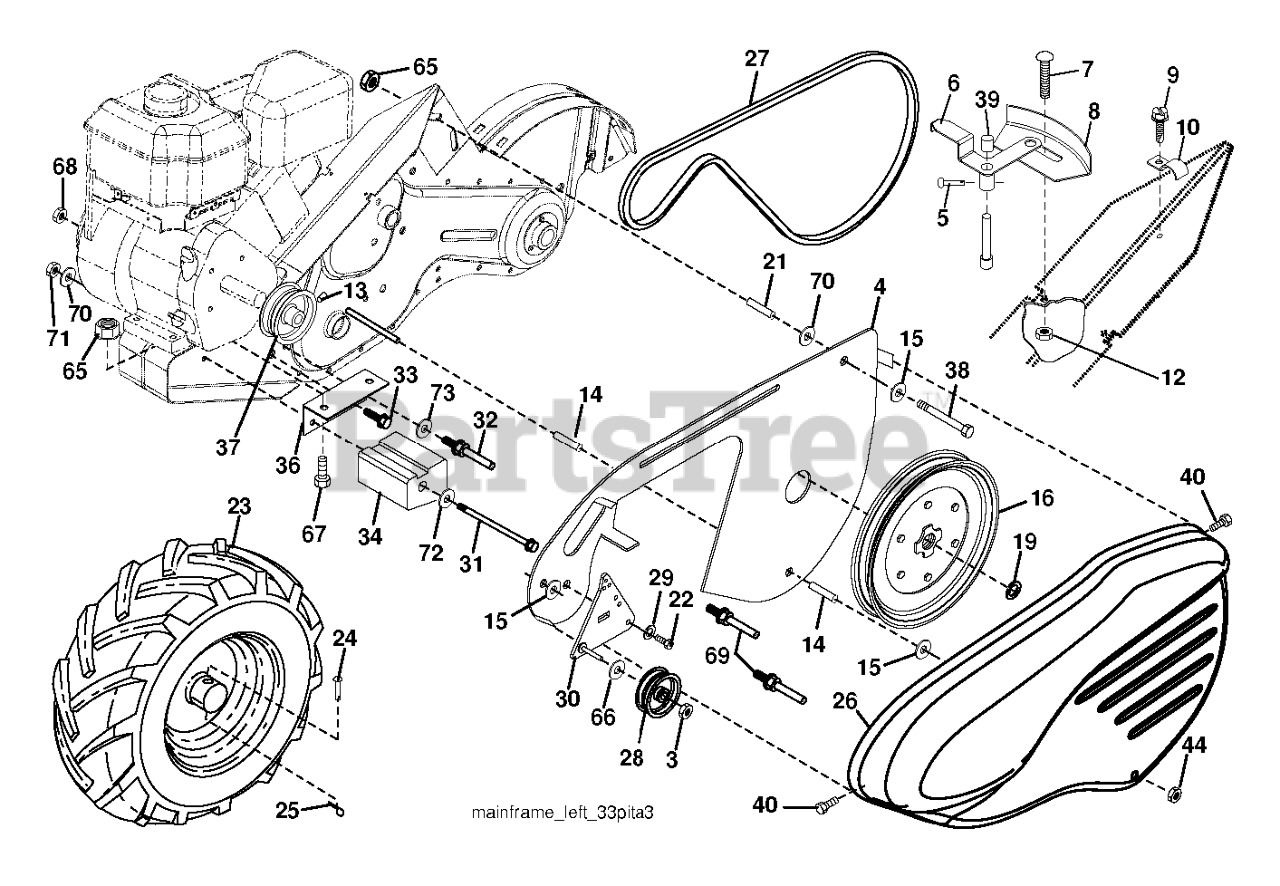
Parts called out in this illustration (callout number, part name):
1	DECK.WELDMENT.54"MS418
3	LOCKNUT
4	SHIELD.INNER.BELT.GUARD.RT.BLA
5	PIN.SPIROL.FLARED
6	COVER.MANDREL.LH.54"20
6	LEVER.ASM.SHIFT.RED
7	COVER.MANDREL.RH.54.20
8	BOLT.WASHER.ASM.7/16-2
8	PANEL.INDICATOR.SHIFT.BLACK.
9	TAPPING SCREW
10	CLIP.PLATED
11	BLADE.BAGGING.54"
12	ROD.ANTI.SWAY.48/54"K4
12	NUT
13	SHAFT ASM MANDREL
14	RP.HOUSING.MANDREL.4PT.
14	SPACER-SPLIT.327 X .42
15	WASHER.FLAT.34X1.38X22
16	WASHER
16	SHEAVE, TRANSMISSION
18	BOLT
19	PIN.COTTER.5/16.BOW TI
19	RETAINING RING LT
21	LOCKNUT
21	SPACER SPLIT
23	WHEEL.ASM.DRT.13X5-6.LT.SILVER
24	CAP-SLEEVE LT
24	RIVET
25	SPRING, TORSION
25	RETAINER M
26	NUT PUSH M
26	GUARD.BELT.TILLER.ORANGE
27	DEFLECTOR
27	V-BELT
28	PULLEY-IDLER TI
29	ROD.HINGE
30	SCREW, WASHER HEAD
30	BRACKET.IDLER.ASM.LONG
31	WASHER.SPACER.MANDREL
31	BOLT.FIN.HEX.3/8-16UNC X 11.5
32	PULLEY/MANDREL
32	SHIFT ARM CRT
33	NUT.FLANGE.LOCK.TOP
33	BOLT
34	COUNTERWEIGHT.LH
36	BRACKET.REINFORCEMENT.LH.PNT
37	RP.ENGINE PULLEY
38	BOLT
39	RB PULLEY.IDLER.4.50/HUB SPEC
39	CAP.PLUNGER.BLACK
40	SCREW.HEX.WSH.SLT.#10-24X.50
43	ARM.IDLER
44	NUT.71038.31-18.HEX.NYLOCK
46	SCREW.1/4-20X5/8
47	RP.BELT.DRIVE.54."2006
49	NUT LOCK FLG 3/8-16 UNC
50	BOLT
52	PULLEY.IDLER.2006
58	BAFFLE.RIGHT.54"
59	BAFFLE.LEFT.54"
60	BAFFLE CENTER 54" MOWER
65	LOCKNUT-FLANGE 5/16-18
66	WASHER
67	BOLT
69	KEEPER.BELT.ENGINE
70	WASHER
72	STEEL WASHER
73	WASHER
98	SPRING, DECK DRIVE
113	BOLT CRT
114	ROD TENSION RELIEF
116	BOLT.SHOULDER.3/8-16X3-5/8.
117	RP WHEEL. GUAGE RALLY
120	WASHER
122	BUSHING.RELIEF.TENSION
185	NUT.LOCK.FLANGE.7/16
187	STUD.FASTNER.W/ANTI-ROTATE
188	NUT LOCK HEX FLANGE 5/16-18
189	ARM.SUSPENSION.MOWER
190	BOLT.SHOULDER
192	KEEPER.BELT.IDLER.54"T
194	BOLT.CARR.SQNK.7/16
196	BOLT
241	SCREW.TT.#10-32X.5.3/8.FLANGE
242	PORT.WASHOUT
